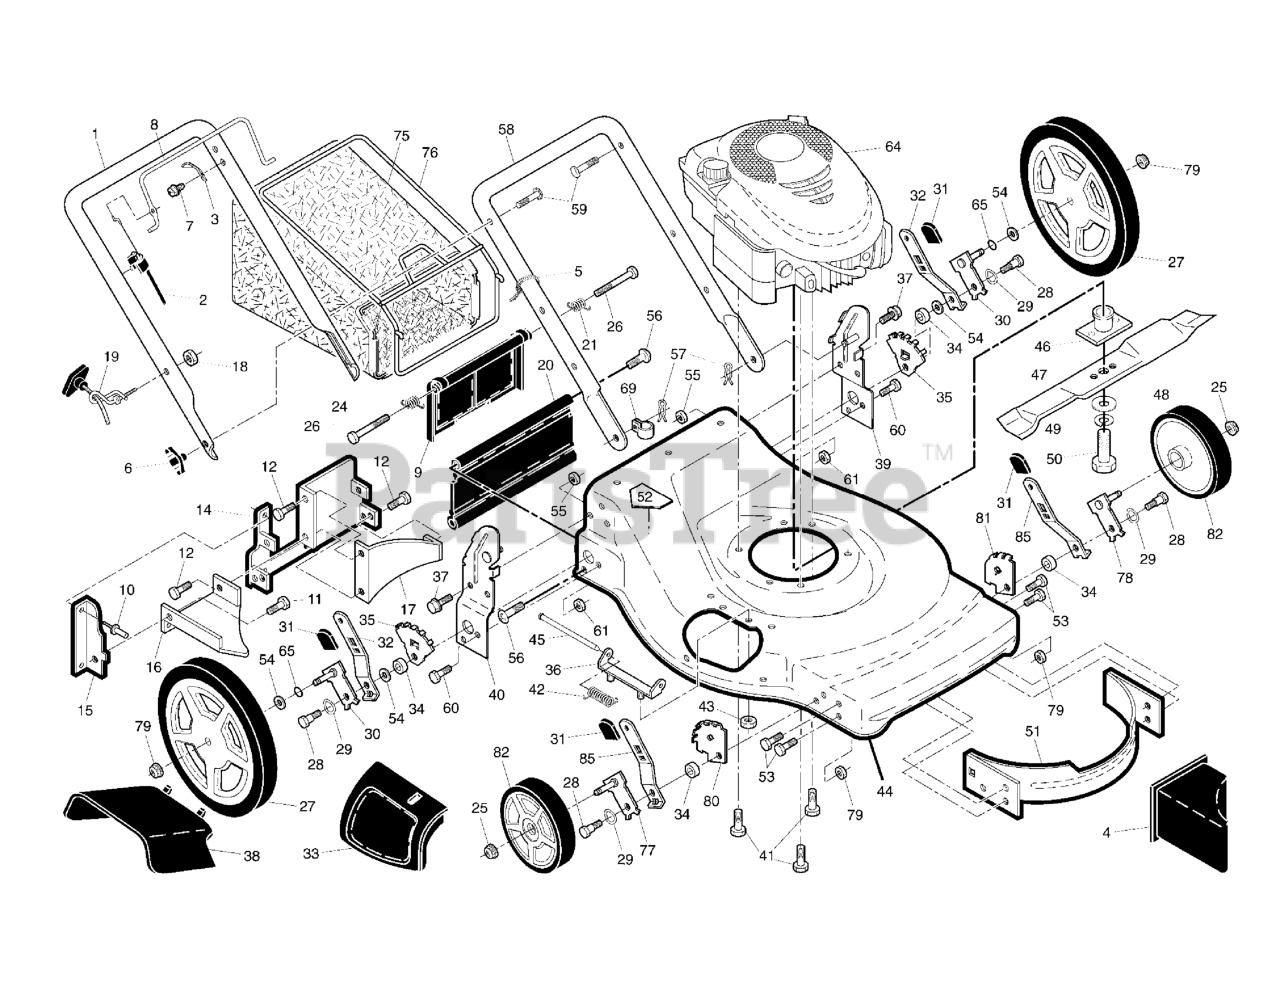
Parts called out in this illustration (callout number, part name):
1	Upper Handle
2	Engine Zone Control Cable
3	Bracket, Upstop
4	Mulcher Plug
5	Wire Tie
6	Handle Knob
8	Control Bar
9	Rear Door Assembly
10	Pop Rivet
11	Screw, Self-Tapping, #10-24 x 5/8
12	Screw, Hex Hex Head, Sems, 1/4-20 x 5/8
14	Back Plate
15	Side Baffl e
16	Discharge Baffle
17	Rear Baffle
18	Keps Locknut 1/4-20
19	Rope Guide
20	Rear Skirt
21	Spring, Rear Door, LH
24	Spring, Rear Door, RH
25	Nut, Hex, Flanged
26	Bolt, Rear Door
27	Wheel & Tire Assembly, Rear
28	Bolt, Shoulder 3/8-16 x 1
29	Washer, Curved, Cylindrical
30	Axle Arm Assembly, Rear
31	Selector Knob
32	Selector Spring, Rear
33	Mulcher Door
34	Spacer
35	Wheel Adjusting Bracket, Rear
36	Hinge Bracket Assembly
37	Screw
38	Discharge Deflector
39	Handle Bracket Assembly, LH
40	Handle Bracket Assembly, RH
41	Screw, Hex Head, Threaded, Rolled, 3/8-16 x 1-1/5
42	Spring, Torsion
43	Nut, Hex, Nylock
44	Kit, Lawn Mower Housing (Includes Ref. Nos. 14, 15 & 51)
45	Rod, Hinge
46	Blade Adapter
47	Blade, 22"
48	Washer, Hardened
49	Washer, Helical
50	Screw, Machine, Hex Head, 3/8-24 x 1-3/8, G8
51	Kit, Front Baffle (Includes Ref. No 53)
52	Danger Decal
53	Screw, Serrated, Type TT, 1/4-20
54	Washer, Flat
55	Locknut, Hex 3/8-16
56	Hinge Screw 1/4-20 x 1-1/4
57	Hairpin Cotter
58	Lower Handle
59	Handle Bolt
60	Bolt, Hex Head 3/8-16 x 3/4
61	Locknut, Hex 3/8-16
64	* Engine, Briggs & Stratton
65	O-Ring
69	Clip, Cable
75	Grassbag Assembly
76	Frame, Grassbag
77	Axle Arm Assembly, Front, RH
78	Axle Arm Assembly, Front, LH
79	Locknut, Hex 1/4-20
80	Wheel Adjusting Bracket, Front, RH
81	Wheel Adjusting Bracket, Front, LH
82	Wheel & Tire Assembly, Front
85	Selector Spring, Front
